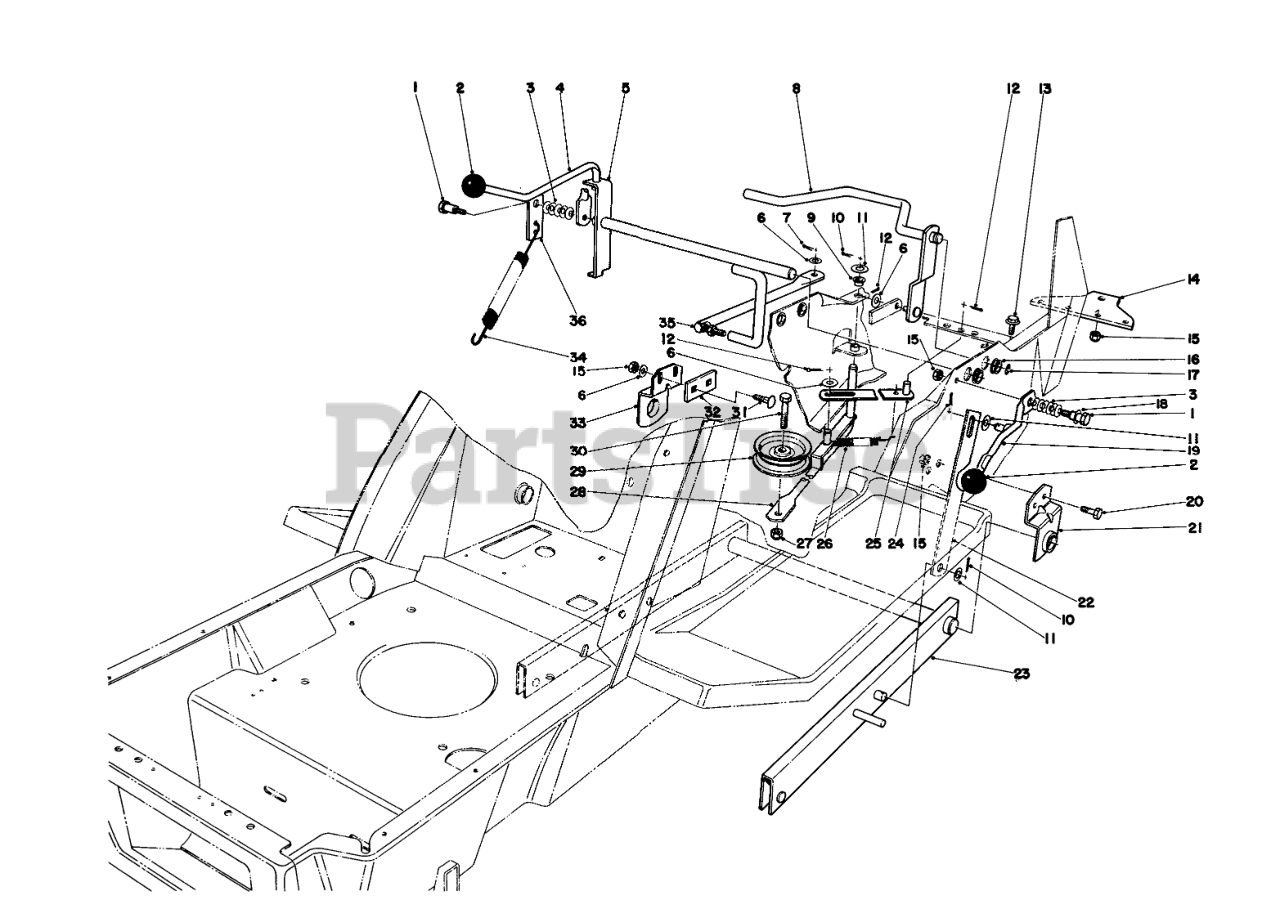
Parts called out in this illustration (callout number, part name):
1	BOLT-SHOULDER
3	WASHER-BELLEVILLE
4	SHIFT LEVER BO
5	Shim Lever
6	WASHER-PLAIN
7	PIN-COTTER
8	CLUTCH ACTUATOR WA B
9	BUSHING-NYLINER
10	PIN-COTTER
11	WASHER-FLAT
12	PIN-COTTER
13	SCREW-HHF
14	HITCH PLATE R
15	NUT-LOCK, CONE
16	Nyliner
17	E-RING
18	WASHER-FLAT
19	HOC HANDLE WA B
20	SCREW-HH
21	Retainer-Pivot Bar L.H.
22	H.O.C. STRAP B
23	Bar-Pivot
24	PIN-COTTER
25	SPRING RET WA B
26	DECK TENSION SPRNG O
27	NUT-LOCK, CONE
28	IDLER ARM WA BO
29	IDLER PULLEY
30	SCREW-HH
31	BOLT-CARR
32	SPACER
33	RH PIVOT BAR RET B
34	TRACTION SPRING
35	SHIFT ARM BO
36	BRKT-COBALANCE SPRING
